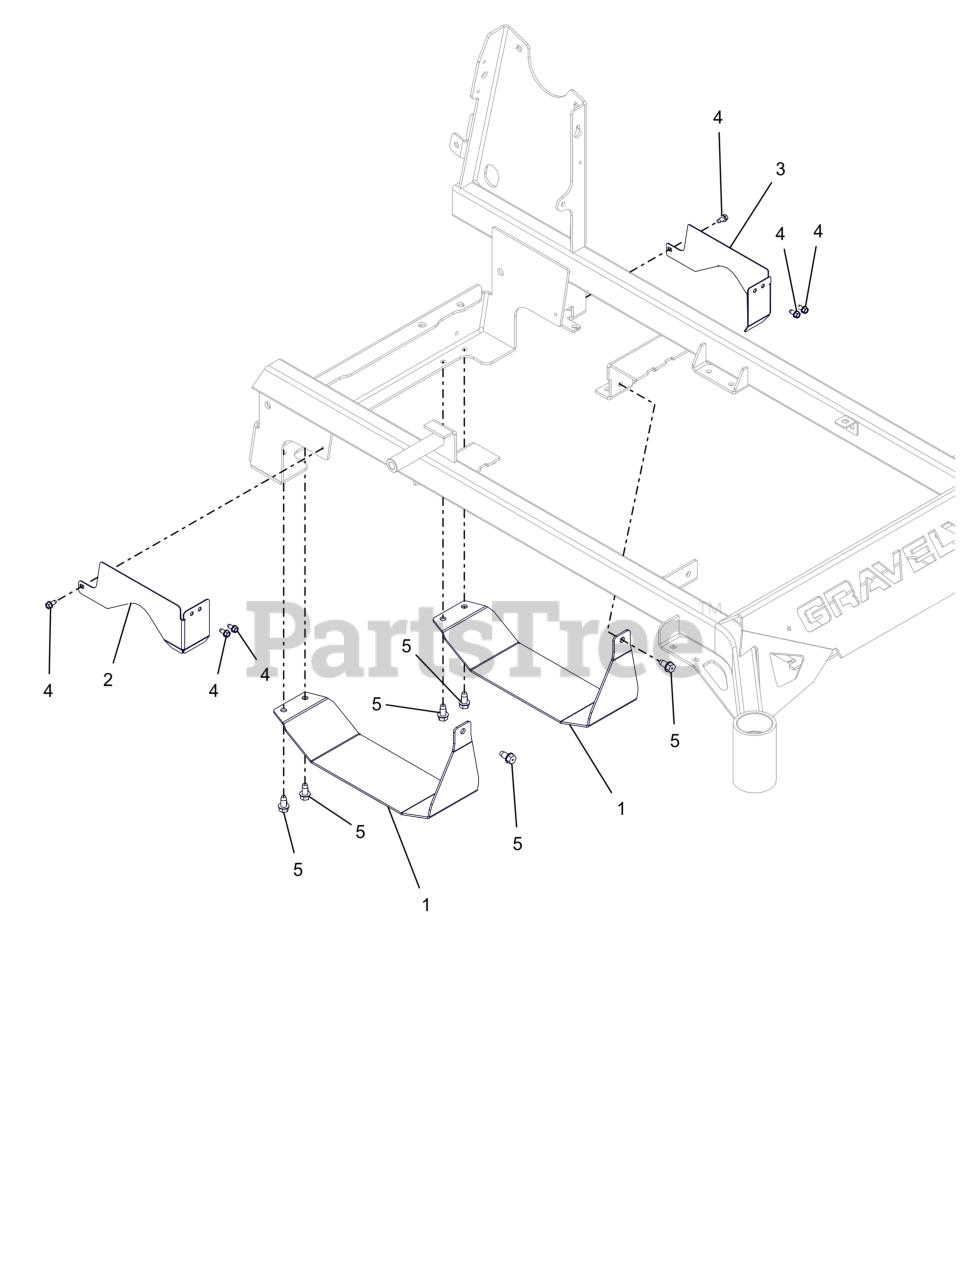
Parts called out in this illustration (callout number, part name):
1	BRKT, SKID PLATE
2	BRKT, RH TRANSAXLE GUARD (BLACK)
3	BRKT, LH TRANSAXLE GUARD (BLACK)
4	SCR-TAP .25-20X.50 HWH ZCC
5	SCR,TAP .375-16X.75 HWH TR ZCC
